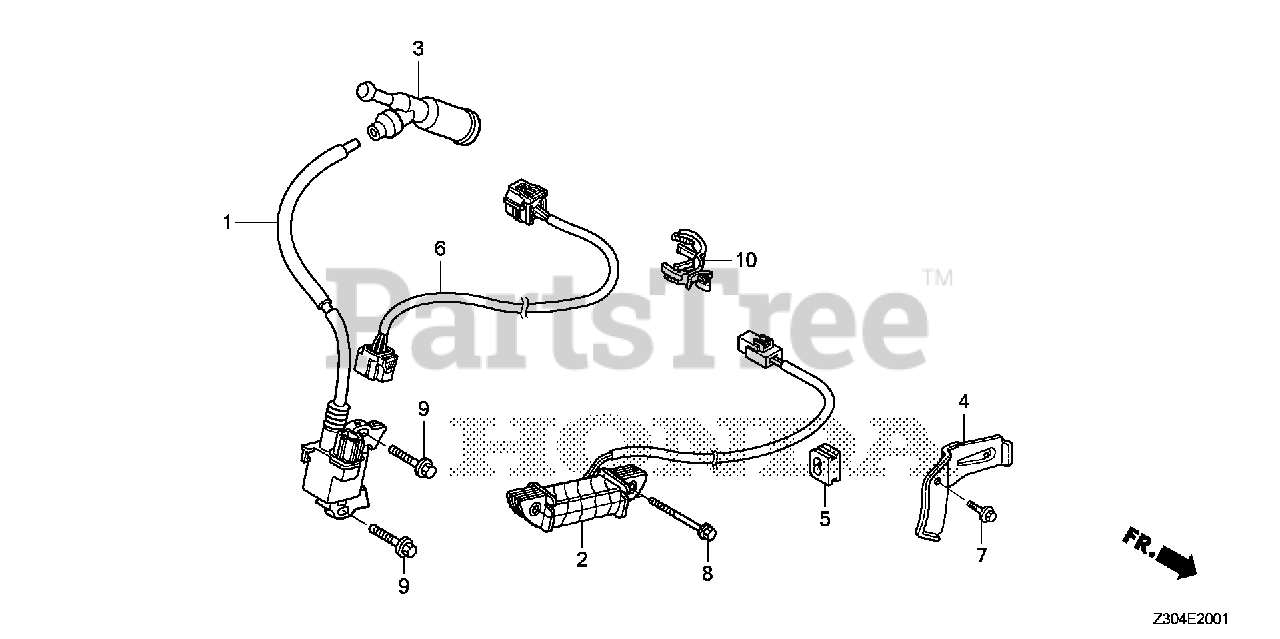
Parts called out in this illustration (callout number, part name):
1	COIL ASSY., IGNITION
1	COIL ASSY., IGNITION (IIDA)
2	COIL ASSY., POWER
3	CAP ASSY., NOISE SUPPRESSOR (NGK Y-EZD)
4	CLAMP, WIRE
5	GROMMET, WIRE
6	WIRE HARNESS ASSY., ENGINE
7	BOLT, FLANGE (6X12) (CT200)
8	BOLT, FLANGE (6X32)
9	BOLT, FLANGE (6X28) (CT200) Use up to Engine SN 1530314.
10	CLIP, WIRE HARNESS
